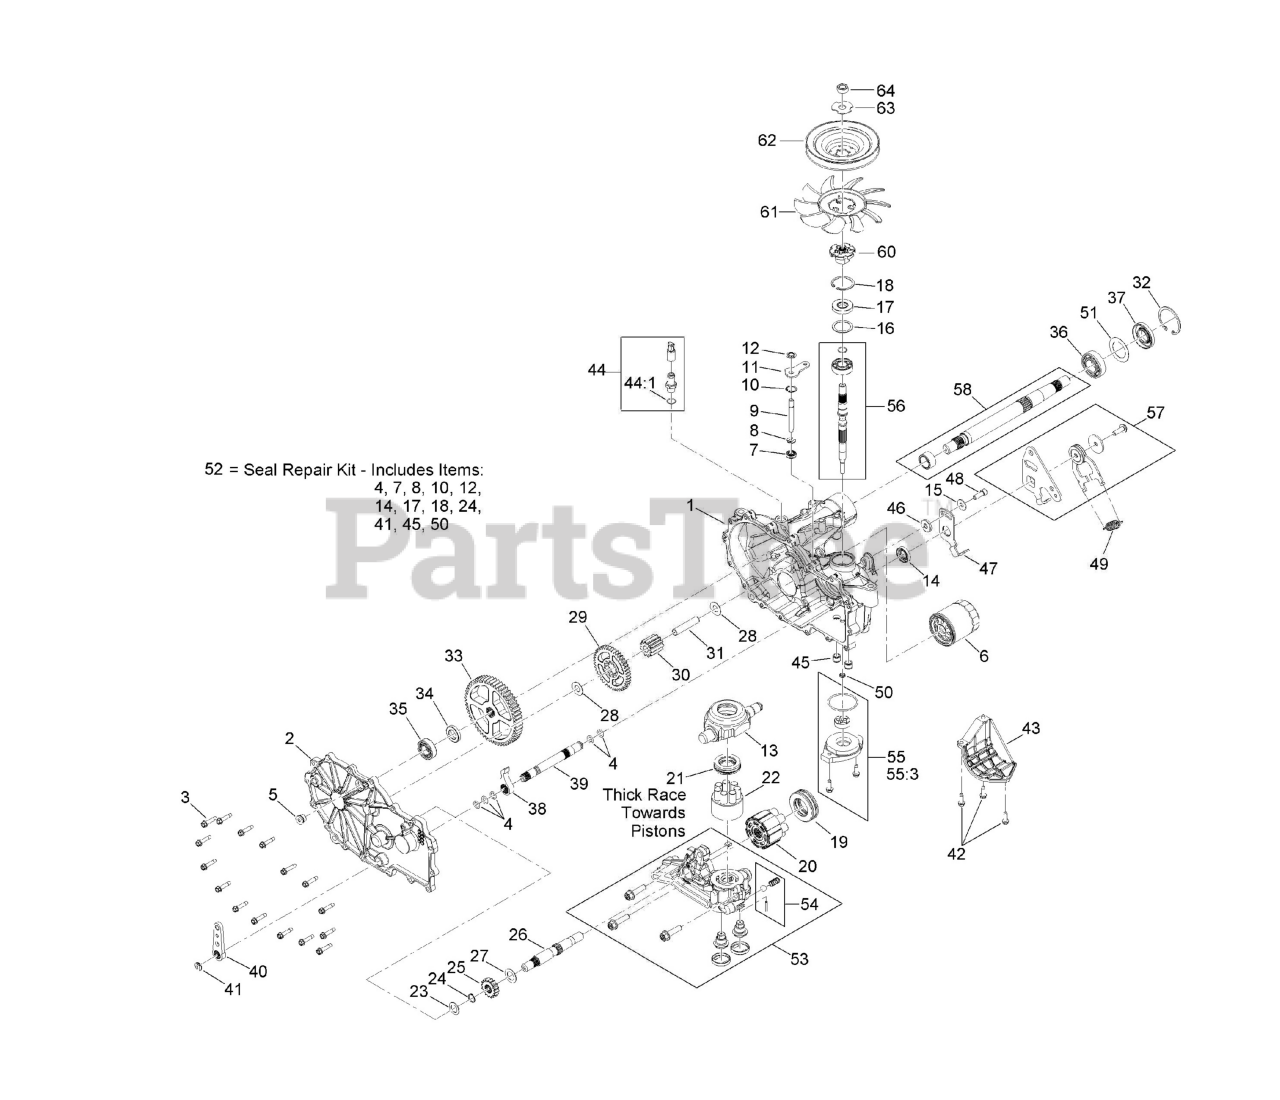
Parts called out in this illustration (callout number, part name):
1	LH MAIN HOUSING KIT
2	LH SIDE COVER KIT
3	SCREW-HHF
6	ELEMENT-OIL FILTER, HYD
7	SEAL-LIP
8	RING-RETAINING, EXTERNAL
9	ROD-BYPASS
10	RING-RETAINING, INTERNAL
11	ARM-BYPASS
12	RING-RETAINING, EXTERNAL
13	SWASHPLATE-TRUNNION
14	SEAL-LIP
17	SEAL-LIP
18	RING-RETAINING
19	BEARING-THRUST
20	MOTOR CYLINDER BLOCK KIT
21	BEARING-THRUST
22	PUMP BLOCK ASM
23	WASHER-FLAT
24	RING-RETAINING
25	GEAR-16T
26	SHAFT-MOTOR
29	GEAR-43T
30	GEAR-11T
31	PIN-JACKSHAFT
32	RING-RETAINING
33	GEAR-54T
35	BEARING-BALL
36	BEARING-BALL
38	PAWL-BRAKE
39	SHAFT-BRAKE, INBOARD
40	HANDLE-BRAKE
41	RING-RETAINING, EXT
43	GUARD-FILTER, RH
44	ADAPTER-STRAIGHT
44:1	O-RING
47	ARM-NEUTRAL, RIGHT
48	SCREW-SH
49	SPRING-EXTENSION
50	Seal-Gerotor
52	SEAL KIT
53	LH CENTER SECTION CHARGE
54	CHARGE RELIEF KIT
55	CHARGE KIT
55:3	O RING-SEAL
56	INPUT SHAFT KIT
57	CONTROL ARM KIT
58	AXLE SHAFT KIT
60	HUB-PULLEY
63	WASHER-SLOTTED
